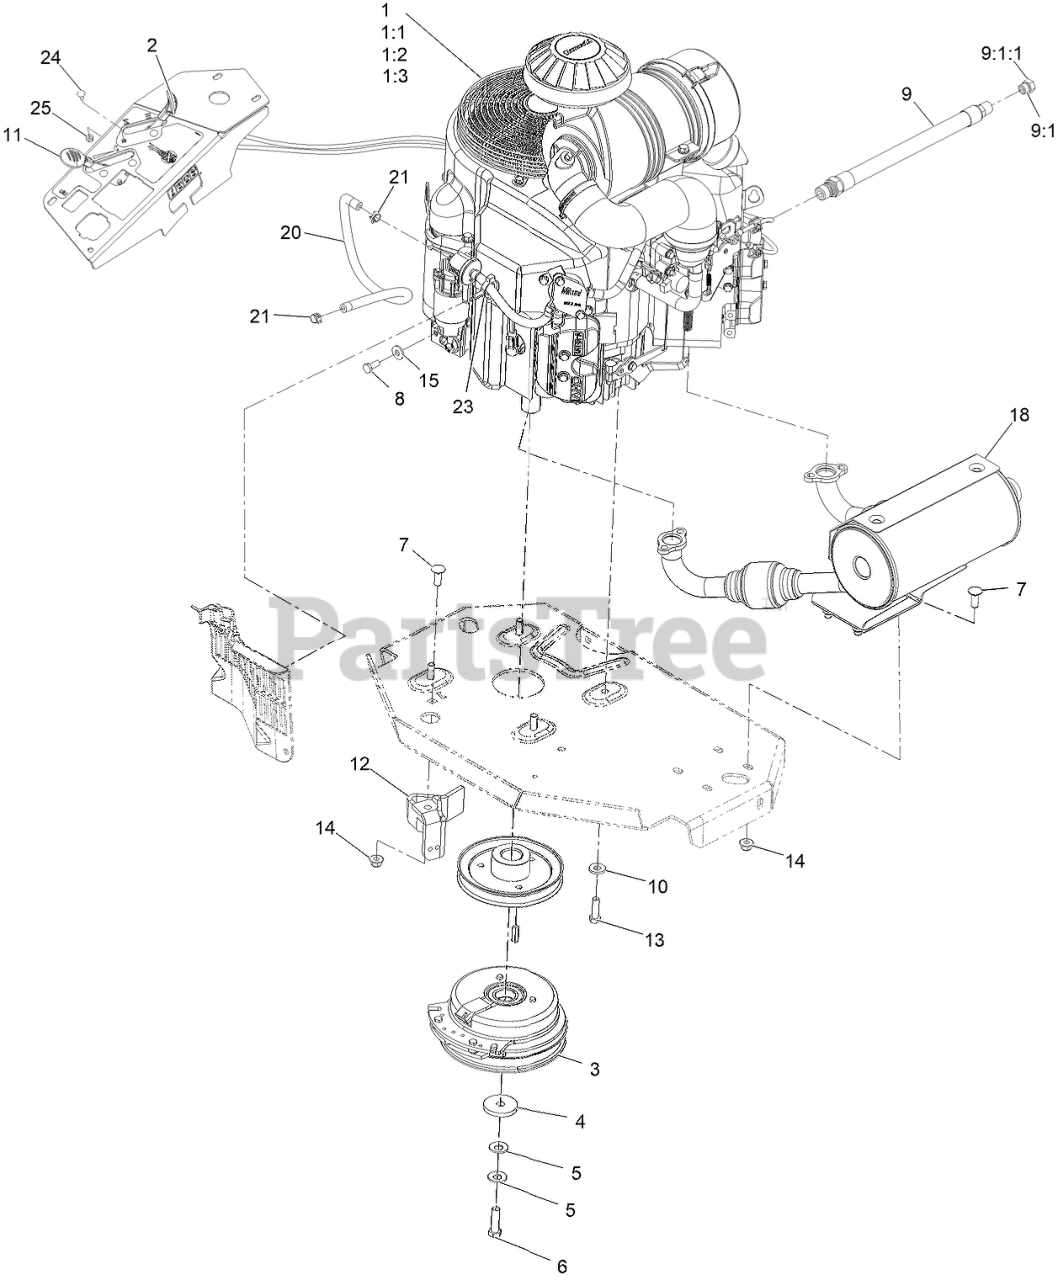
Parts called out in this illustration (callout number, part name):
1:1	Kawasaki 49065-7010 Engine Oil Filter
1:2	Kawasaki 11013-7044 Engine Air Filter
1:3	Kawasaki 11013-7045 Safety Filter
2	ASM, CHOKE CABLE
3	CLUTCH KIT
4	WASHER-CLUTCH
5	WASHER-SPRING
6	SCREW-HH 7/16-20 X 1 1/2 W/LOCTITE
7	SCREW-CARR
8	SCREW-HH
9	ENGINE OIL DRAIN HOSE ASM
9:1	PLUG-HH
9:1:1	O-RING
10	WASHER-BELLEVILLE
11	ASM,THROTTLE CABLE
12	CLUTCH-ANCHOR
13	SCREW-HH
14	NUT-HF, NI
15	WASHER-SPRING
18	KIT, MUFFLER
20	HOSE-FUEL
21	CLAMP-HOSE
23	CLAMP-HOSE
24	BOLT-CARR
25	NUT-LOCK, NI
